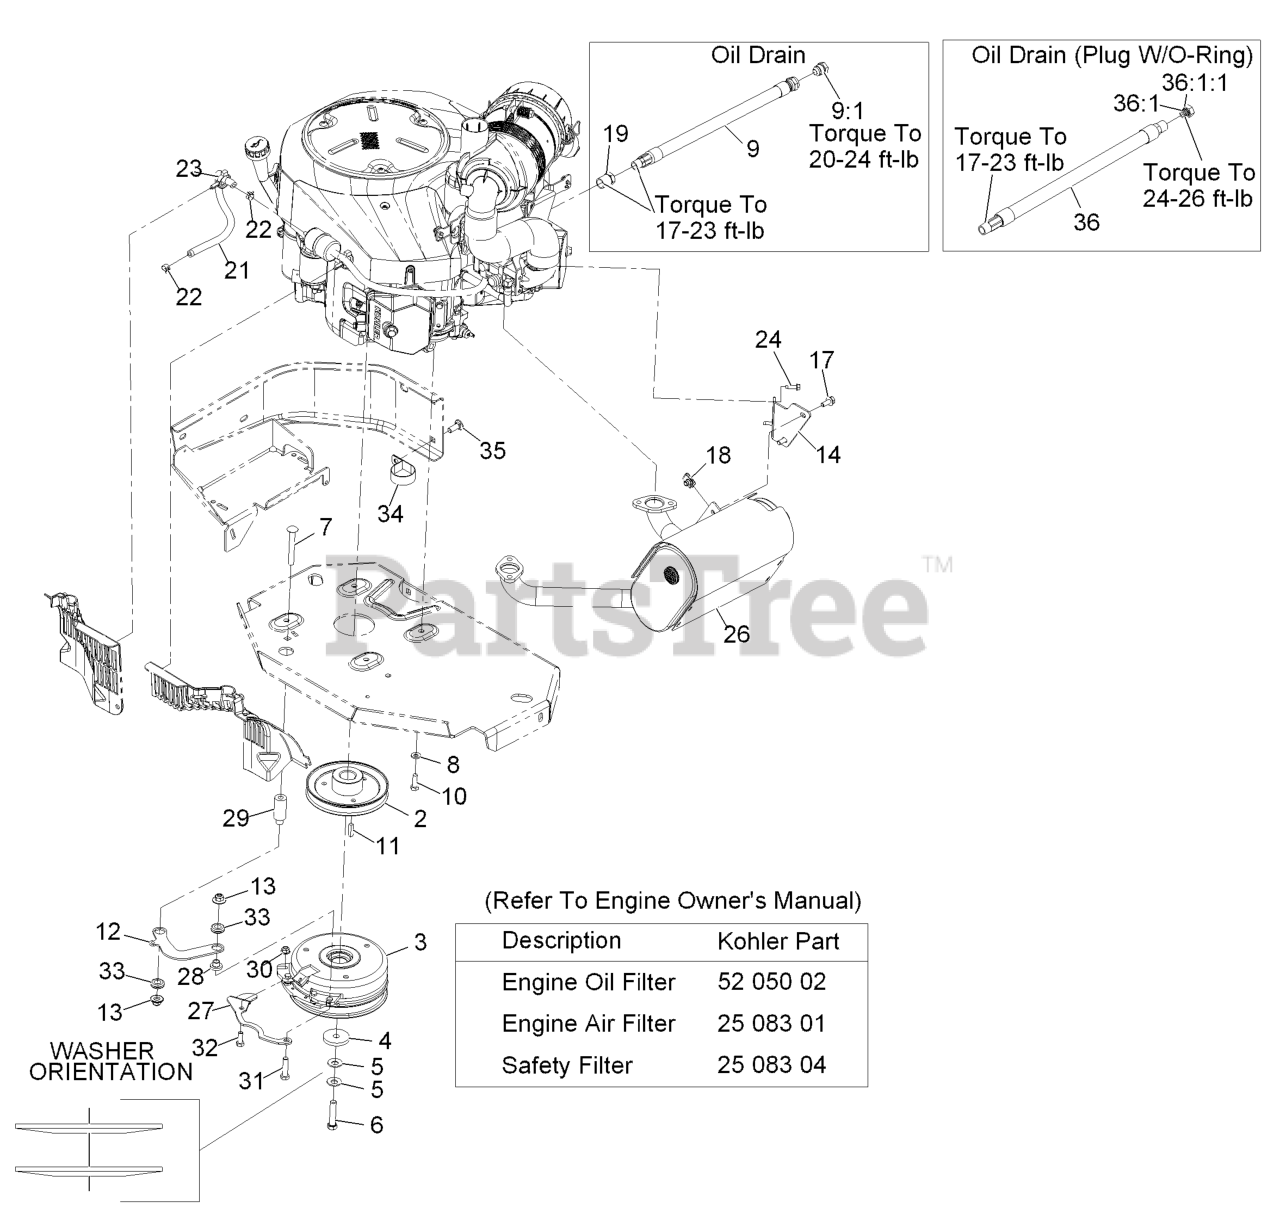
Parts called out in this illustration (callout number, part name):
2	SHEAVE
4	WASHER-CLUTCH
5	WASHER-SPRING
6	SCREW-HH W/LOCTITE
7	SCREW-CARR
8	WASHER-SPRING
10	SCREW-HH
12	LINK-ANCHOR, CLUTCH
13	Nut-Nyloc 3/8-16 Flg
17	SCREW-HHF
19	BUSHING
22	CLAMP-HOSE
23	CLAMP-HOSE
26	MUFFLER
27	BELT-GUIDE
30	NUT-HF, NI
31	SCREW-HH
32	SCREW-HH
33	GROMMET-RUBBER
34	CLAMP-R
35	SCREW-CARR
36	OIL DRAIN HOSE ASM
36:1	PLUG-HH
36:1:1	O-RING
